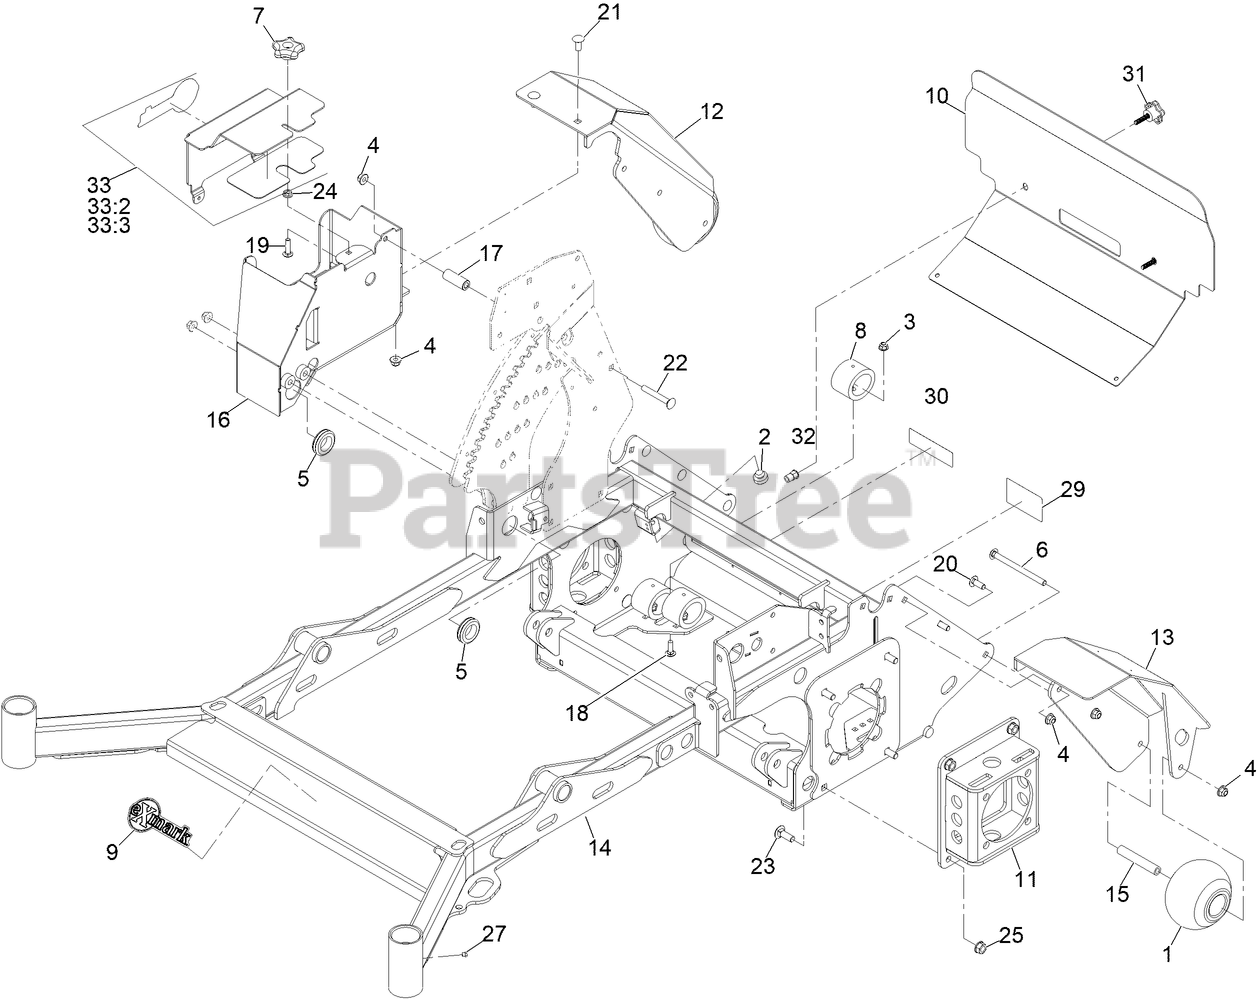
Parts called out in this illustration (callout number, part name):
1	ROLLER-SCALP, ANTI
2	BUMPER-RUBBER
3	NUT-HF, NI
4	NUT-HF, NI
5	GROMMET
6	BOLT-CARR
7	KNOB-HANDLE
8	BUMPER-ISOLATOR
9	DECAL-EXMARK LOGO
10	GUARD-REAR FOOT
11	WLD-MTR MOUNT 60
12	FENDER- WHEEL RH
13	FENDER- WHEEL LH
14	Mainframe ASM - 60
15	SPACER- ROLLER
16	WELD-BATTERY BOX
17	SPACER- ROLLER
18	BOLT-CARR
19	SCREW-CARR
20	SCREW-CARR
21	SCREW-CARR
22	SCREW-CARR
23	BOLT-CARR
29	DECAL-DRIVE RELEASE
30	DECAL-COVER, MISSING
32	NUT-CLINCH
33	ASM-LID BATTERY W/PAD
33:2	PAD-BATTERY BOX LID
33:3	DECAL-EXMARK LOGO
